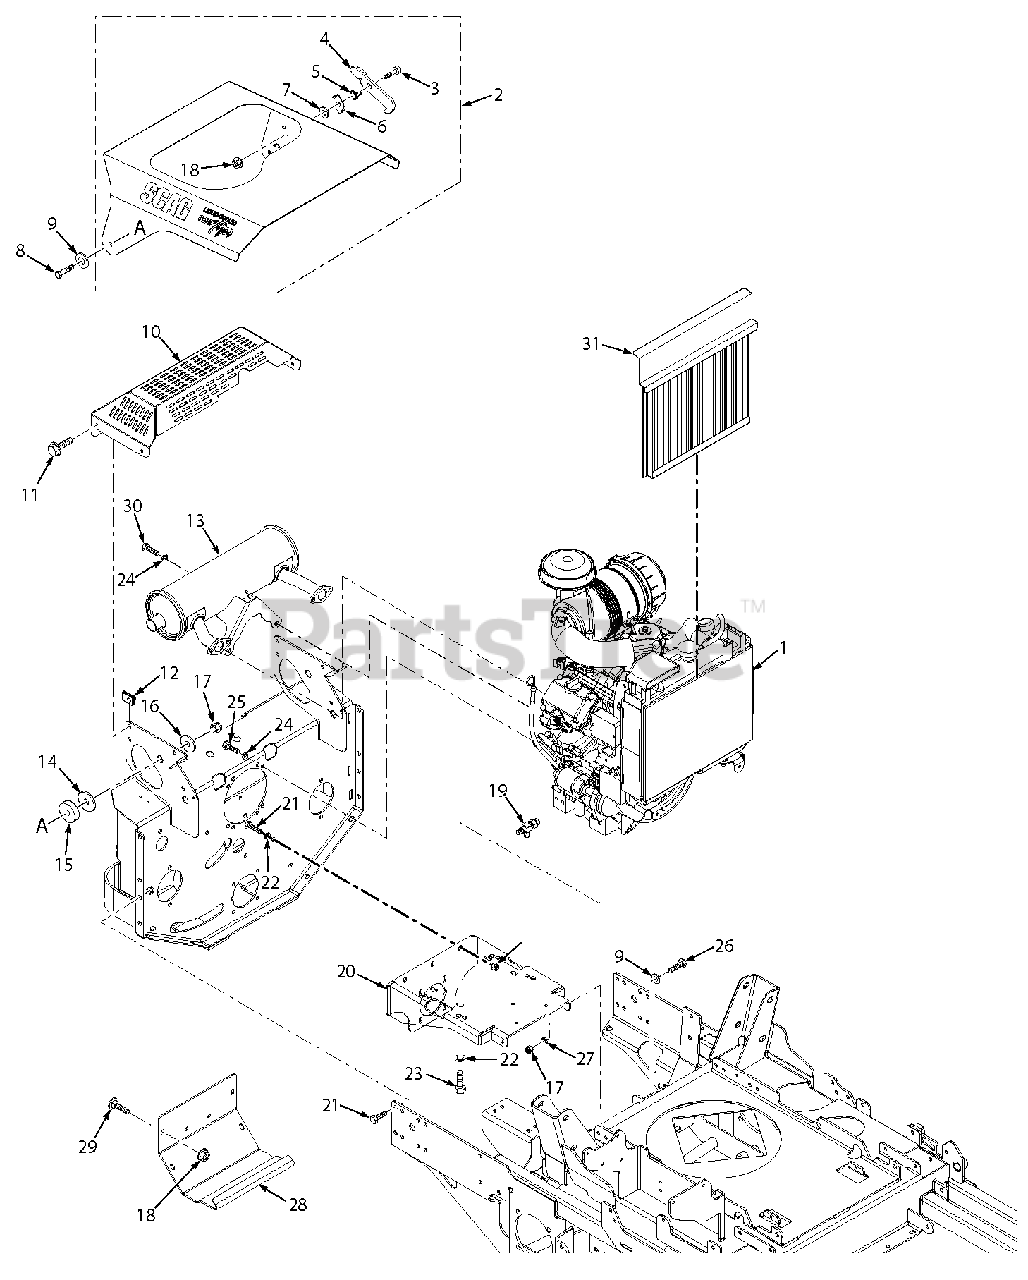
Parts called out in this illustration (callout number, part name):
1	Engine, FD750 - Kawasaki
1	Engine, FD791 - Kawasaki
1	Engine, FD850 - Kawasaki
2	Hood Assy., STTII (FD750)
2	Hood Assy., STTII (FD791 & FD850) - Fuel Injected
3	Bolt, Shoulder 3/8 x 1/2
4	Latch, Hood
5	Spring, Hood Latch
6	Lock, Hood Latch
7	Flatwasher, 3/8-.406 x .812 x .065
8	Bolt, Hex Head 3/8-16 x 1-3/4"
9	Flatwasher, 3/8-.406 x .812 x .065
10	Guard, Muffler
11	Bolt, Hex Head Serrated Flange 1/4-20 x 3/4"
12	U-Nut, 1/4-20
13	Muffler, Kawasaki
14	Disk, Anti-Friction
15	Spacer, Hood
16	Flatwasher, 3/8-.406 x 1.50 x 7 Gauge
17	Nut, Elastic Stop 3/8-16
18	Nut, Serrated Flange 5/16-18
19	Oil Drain, Kawasaki
20	Plate Weldment, Engine Mount
21	Bolt, Hex Head 3/8-16 x 1"
22	Lockwasher, 7/16
23	Bolt, Hex Head M10-1.5 x 25 fULL Thread
24	Lockwasher, 5/16
25	Bolt, Hex Head M8-1.25 x 20
26	Bolt, Hex Head 3/8-16 x 1-1/4"
27	Lockwasher, 3/8
28	Cover, Rear
29	Bolt, Carriage 5/16-18 x 3/4"
30	Bolt, Hex Head M8-1.25 X 20
31	Screen Weldment, Radiator
